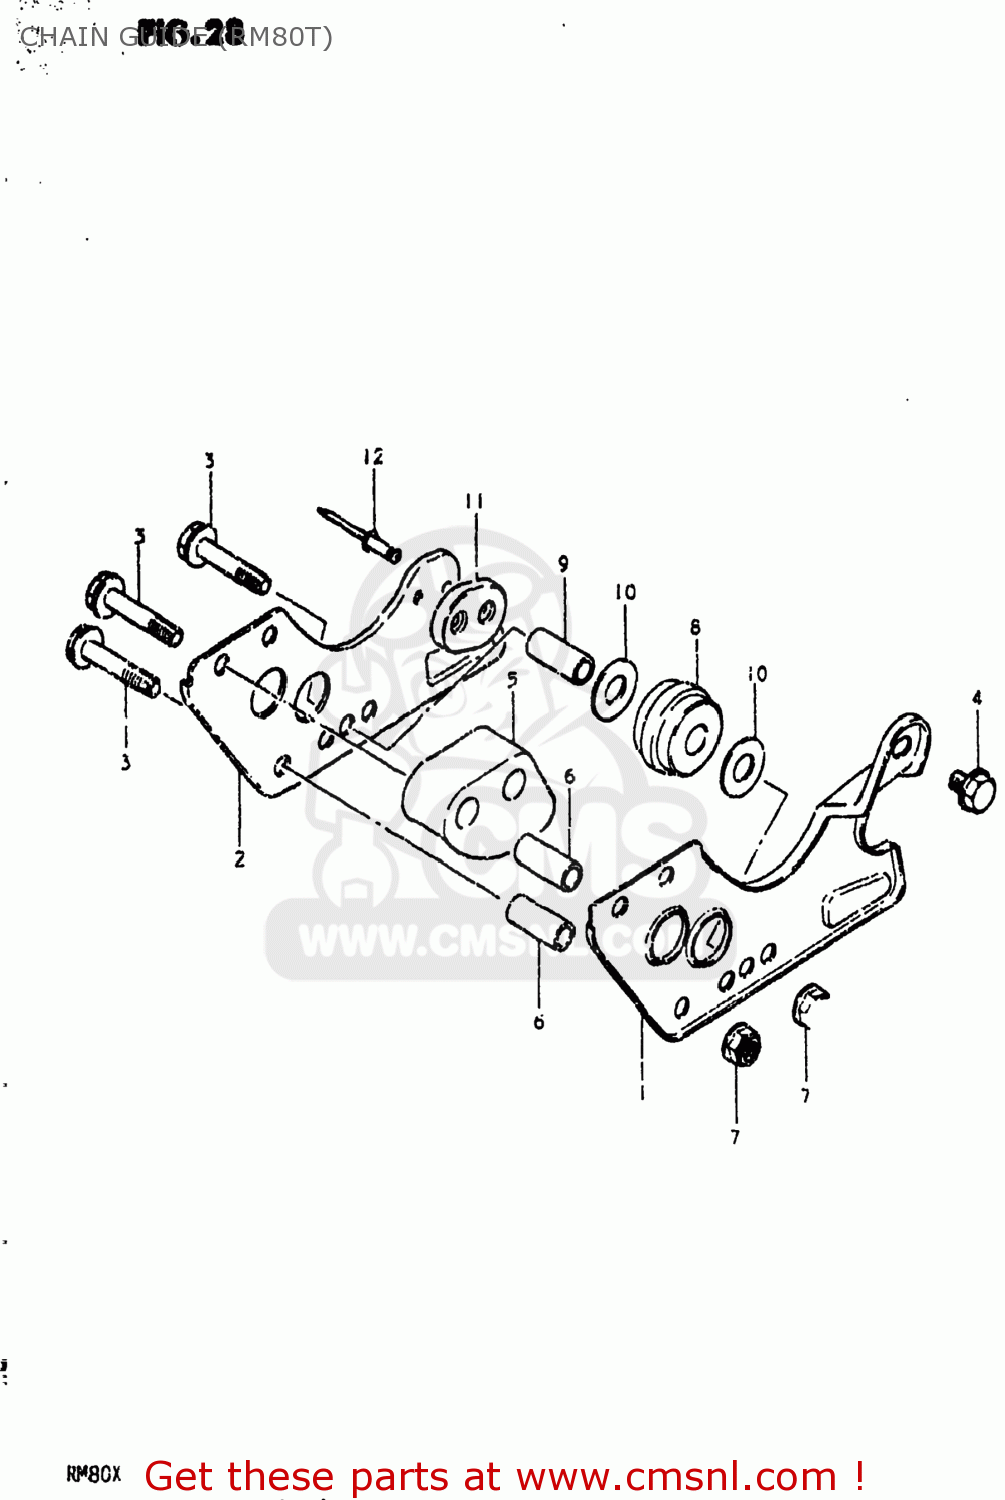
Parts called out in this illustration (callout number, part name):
1	GUIDE,CHAIN
2	PLATE,GUIDE CHAIN
3	BOLT 6X35
4	BOLT
5	ROLLER,CHAIN GUIDE
6	SPACER(6.8X10X24.2)
7	NUT
8	ROLLER,CHAIN GUIDE
9	SPACER,CHAIN GUIDE ROLLER
10	WASHER
11	PAD,DRIVE CHAIN GUIDE
